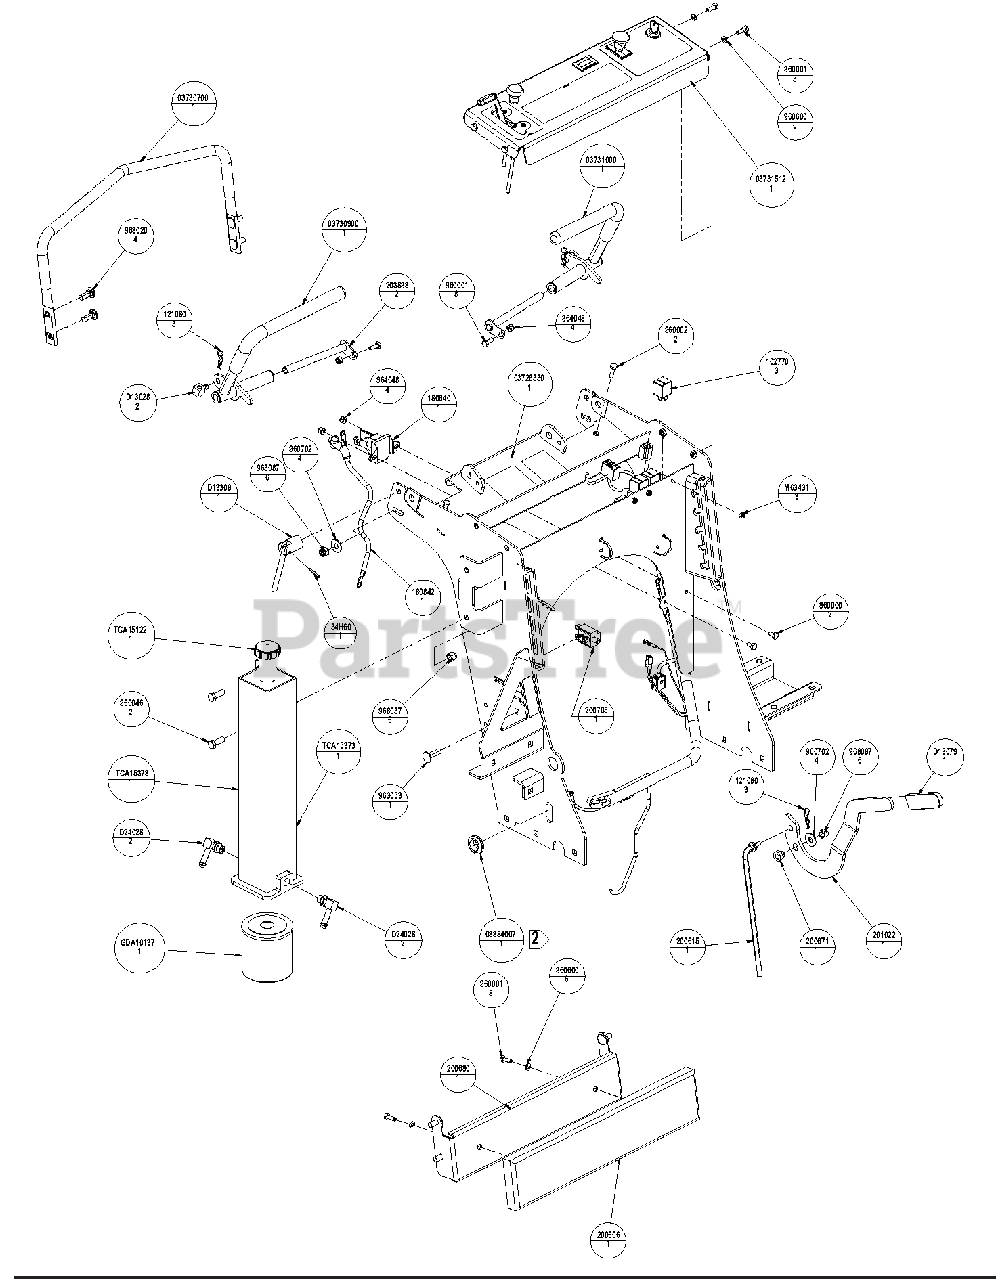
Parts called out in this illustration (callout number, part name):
1	SWIVEL ADJUSTER-THREAD SIZE 5/
2	BASE, LOCK LEVER Y
3	LEVER, LOCK Y
4	GRIP, PVC .250 X 1.00 X 3.63
5	SCREW,8-32X1/2
6	FTG, 90 9/16MOR X 3/8HOSE
7	FTG, 90 ADP JIC-ORB 6801-08-08
8	FILTER, OIL
9	#8.32 ELASTIC STOP NUT
10	CAP, FILLER, OIL
11	WLDT, PIVOT ROD Y
12	RESERVOIR, HYDRAULIC
13	RELAY, ISO MINI ELEC.
14	CABLE TIE, .15 X 8.50
15	PIN, HAR .091X1.63 5/16-1/2 Y
16	SOLENOID, 12V STARTER
17	CABLE, 12" STARTER
18	BRG, FLG .500X.620X.500 BRNZ
19	PAD, THIGH
20	LINK, BRAKE Y
21	ASSEMBLY, CONTROL PANEL EVRIDE
22	SUPPORT, HANDLE PAINTED
23	BUSHING, BRAKE PIVOT Y
24	WLDT, THIGH PAD BRACKET
25	SWITCH, NO-NO-NC GREY PLUNGER
26	BRAKE LEVER, OFFSET
27	WLDT, CONSOLE 34 W/DECALS GOLD
28	RH CONTROL LEVER W/GRIP
29	LH CONTROL LEVER W/GRIP
30	HARNESS, WIRING
31	FTG, 90 9/16MOR X 3/8HOSE
32	PIN, SPRING
33	BOLT, 1/4-20 X .500 HEX 5 Y
34	BOLT, 1/4-20X.750 HEX 5 Y
35	BOLT, 1/4-20X1.00 HEX 5 Y
36	BOLT, 3/8-16X1.00 HEX 5 Y
37	NUT, 1/4-20 STD HEX GR5 Y
38	WASHER, .250 MED SPRG LOCK Y
39	WASHER, .375 REG FLAT Y
40	BOLT, 3/8-16X1.00 CRG 5 Y
41	BOLT, 3/8-16X1.25 CRG 5 Y
42	LOCKNUT, 1/4-20 NYLOC Y
43	LOCKNUT, 3/8-16 NYLOC Y
